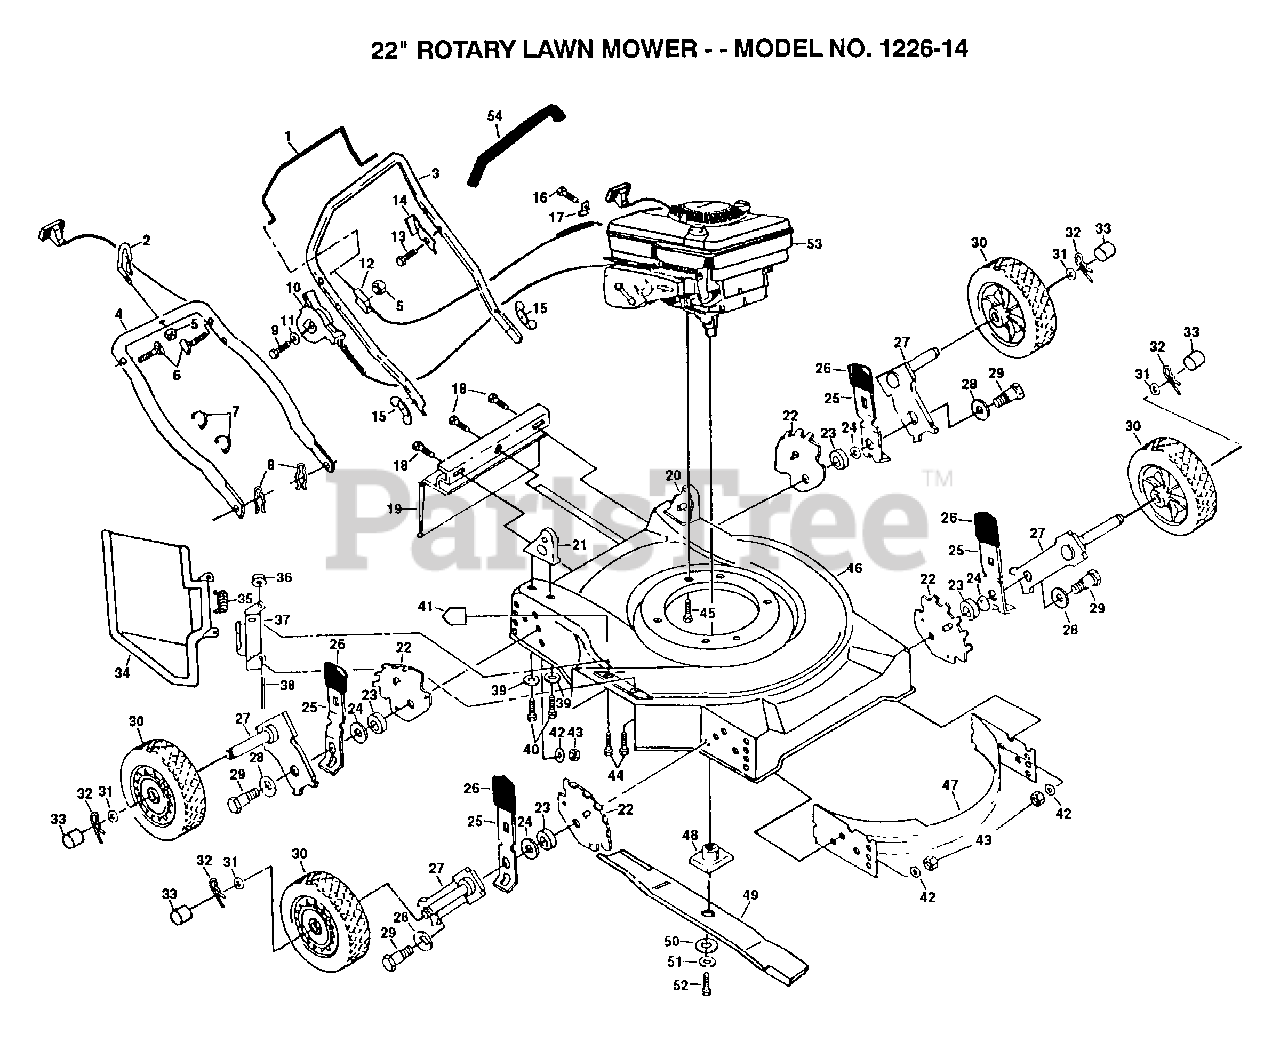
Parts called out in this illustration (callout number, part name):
2	ROPER GUIDE PM
7	CABLE CLIP PM
8	HAIRPIN COTTER
10	CONTROL.THROTTLE
11	WASHER PM
12	CABLE.ZONE.CONTRO
13	TAPPING SCREW
14	"BRKT,UPSTOP"
15	"NUT,WING PM"
16	SCREW PM
17	CABLE CLAMP
18	SCREW
19	REAR SKIRT M
24	WASHER PM
26	KNOB PM
27	AXLE ARM
28	"WASHER, BELLEVIL."
30	WHEEL.ASM
31	WASHER
32	RETAINER CLIP PM
33	HUB CAP-PLASTIC
35	"SPRING,TORSION"
36	PUSH ON SPEED NUT
37	"BRKT,HSG"
38	"ROD,HINGE "
39	STEEL WASHER
40	SCREW
41	DECAL HYT
43	LOCKNUT PM
44	SCREW
45	SCREW
48	BLADE ADAPTOR
49	"BLADE.22"""
50	"WASHER,HARDEN"
51	LOCKWASHER
52	SCREW
